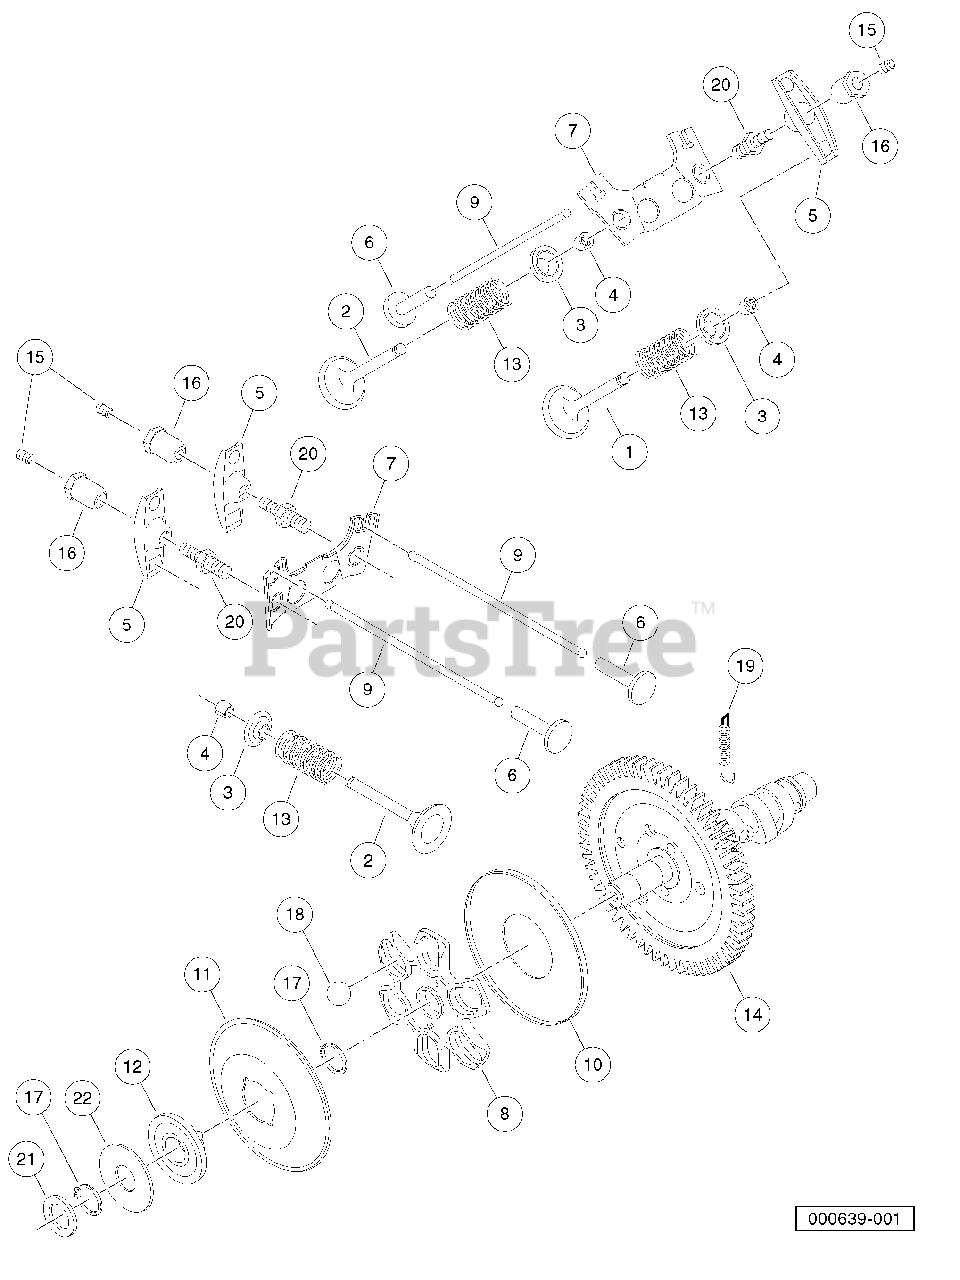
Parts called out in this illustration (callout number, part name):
1	Valve, Intake, Fh
2	Valve, Exhaust, Fh
3	Retainer, Valve Spring, Fh
4	Collet, Spring, Valve, Fh
5	Arm, Rocker
6	Tappet, Rod, Push, Fh
7	Guide, Arm, Rocker, Fh
8	Guide, Camshaft, Gov, Fh
9	Rod, Push, Fh
10	Plate, Camshaft, Gov, Fh
11	Plate, Ring, Gov, Fh
12	Sleeve, Plate, Gov, Fh
13	Spring, Valve, Fh
14	Kit, Camshaft, Comp, Fh
15	Screw, Rocker Arm, Fh
16	Nut, Arm, Rocker, Fh
17	Ring, Snap, Gov, Fh
18	Ball, Guide, Gov, Fh
19	Spring, Camshaft, Fh
20	Stud, Rocker Arm, Fh
21	Washer, Sleeve, Gov, Fh
22	Washer, Gov, Fh
